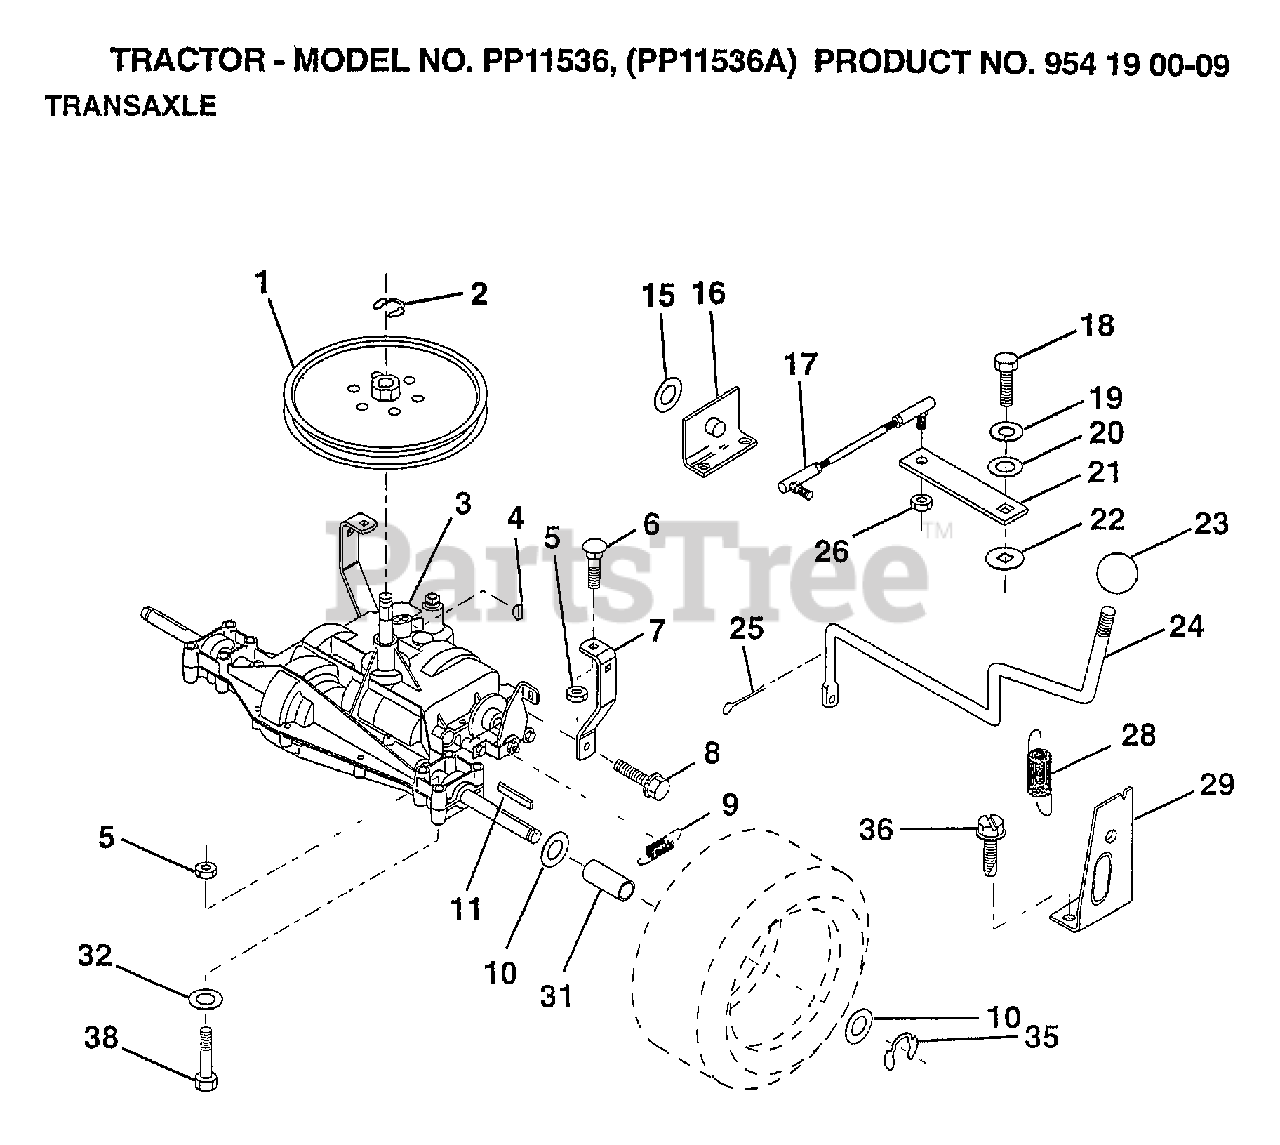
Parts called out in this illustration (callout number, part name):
1	PULLEY
3	TRANSAXLE PEERLESS
6	BOLT
7	"STRAP,TORQUE"
8	SCREW
9	SPRING.BRAKE.RETU
10	WASHER
11	SQUARE KEY
16	SUPPORT HANDLE SHIFT LH
17	LINK SHIFT
18	BOLT.1/4-28.W/PAT
19	LOCKWASHER
20	WASHER LT
22	WASH-SHFT PLT LT
23	KNOB T (1/2-HOLE)
24	"ROD,SHIFT"
25	PIN COTTER 1/8
26	NUT.LOCK.5/16-24
28	"SPRING,EXT"
29	"SUPT,HDLE RH"
31	SPACER AXLE
32	WASHER
35	E-RING LT
36	SCREW
38	BOLT.HX.FLG.5/16
